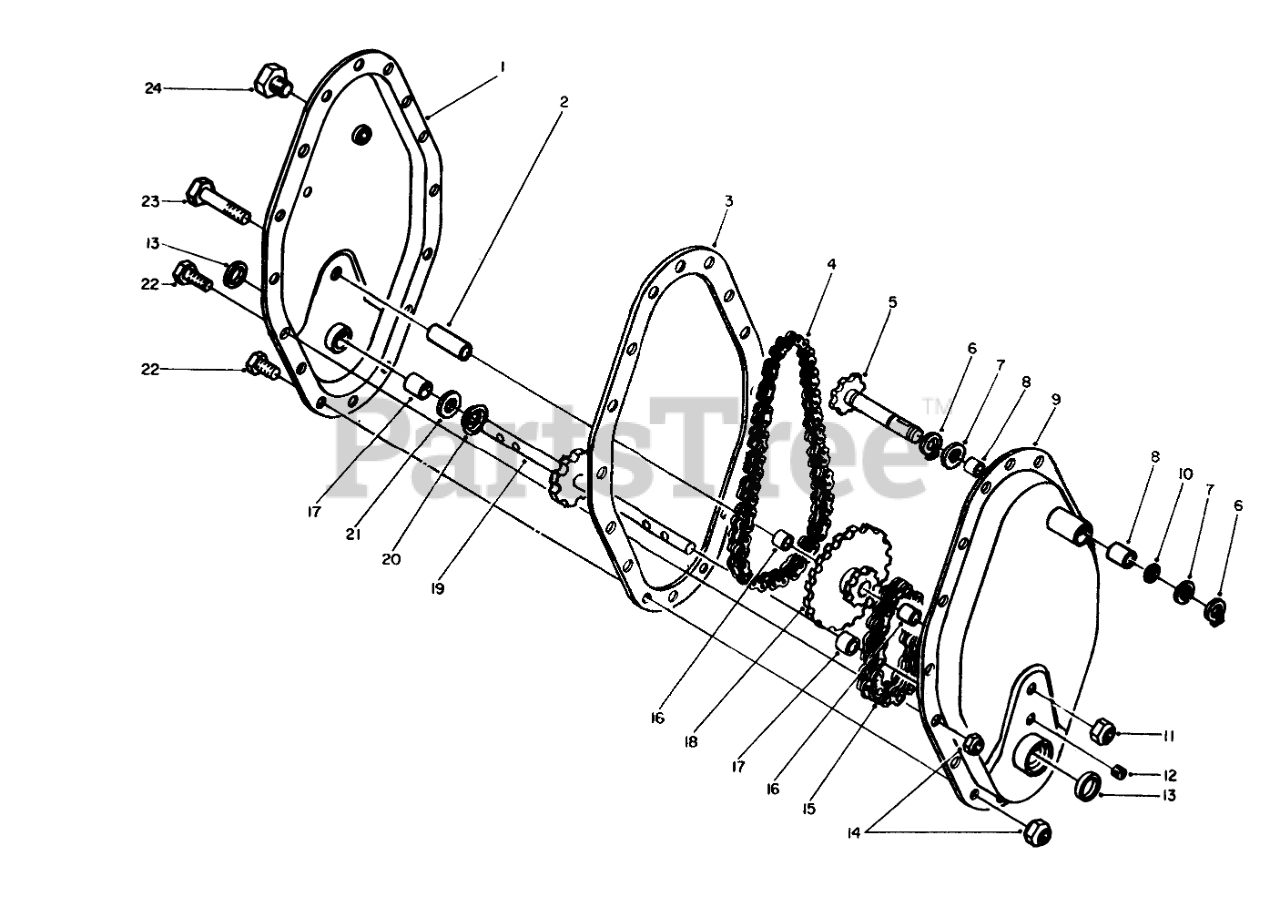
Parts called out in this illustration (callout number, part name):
1	Chain Case R.H. w/Bearings
2	Idler Sleeve
3	Gasket
4	Chain-Upper
5	Input Shaft
6	Retaining Ring
7	Washer
8	BEARING-NEEDLE
9	Chain Case-L.H. w/Bearings
10	Seal
11	NUT-LOCK, CONE
13	Seal
14	NUT-LOCK, CONE
15	Chain-Lower
16	NEEDLE BRG
17	Bearing
18	Sprocket (Incl. Ref. #16)
19	Tine Shaft
20	Spacer Cup
21	Shim-Gear
22	SCREW-HH
23	Capscrew
24	SCREW-HH
